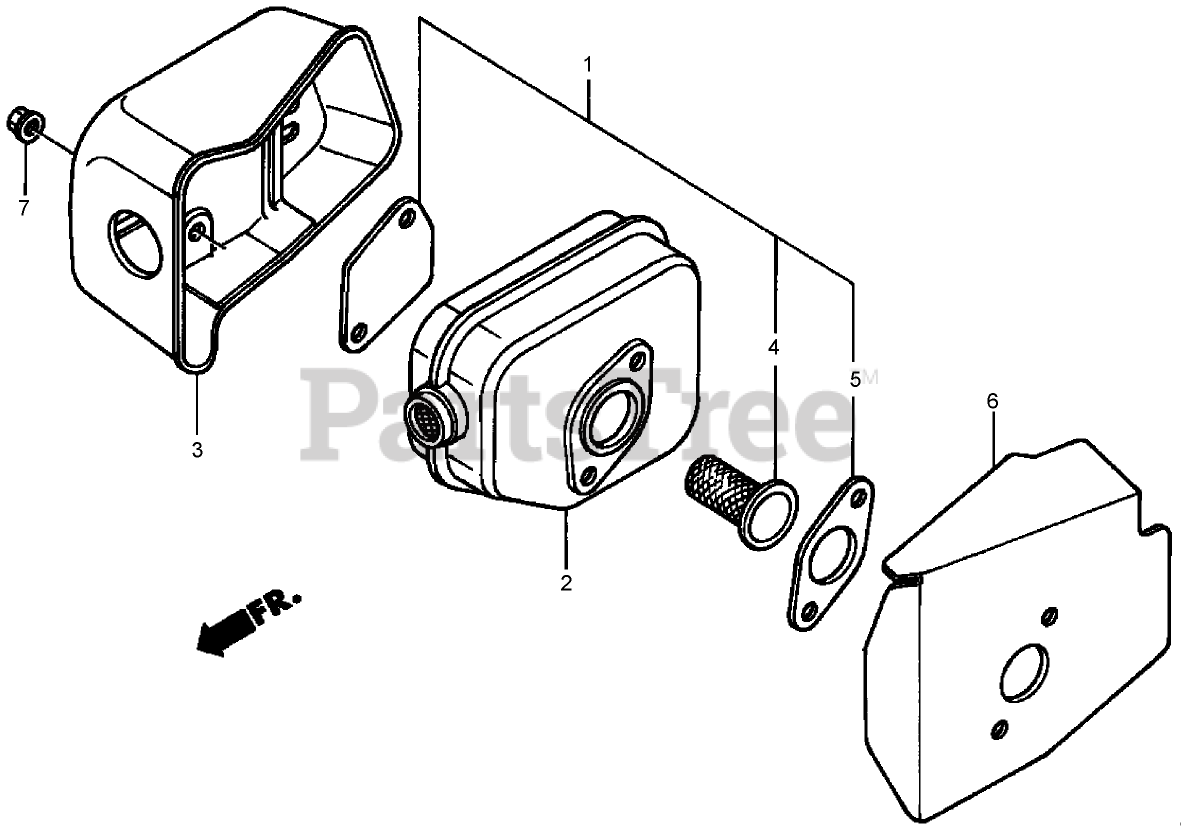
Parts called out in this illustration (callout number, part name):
1	SPARK ARRESTER KIT
2	Muffler
3	Protector-Muffler
4	SPARK ARRESTER KIT
4	SPARK Arrester Kit
5	Gasket-Muffler
6	Gasket-Muffler
7	NUT-LOCK, SELF (6 mm)
